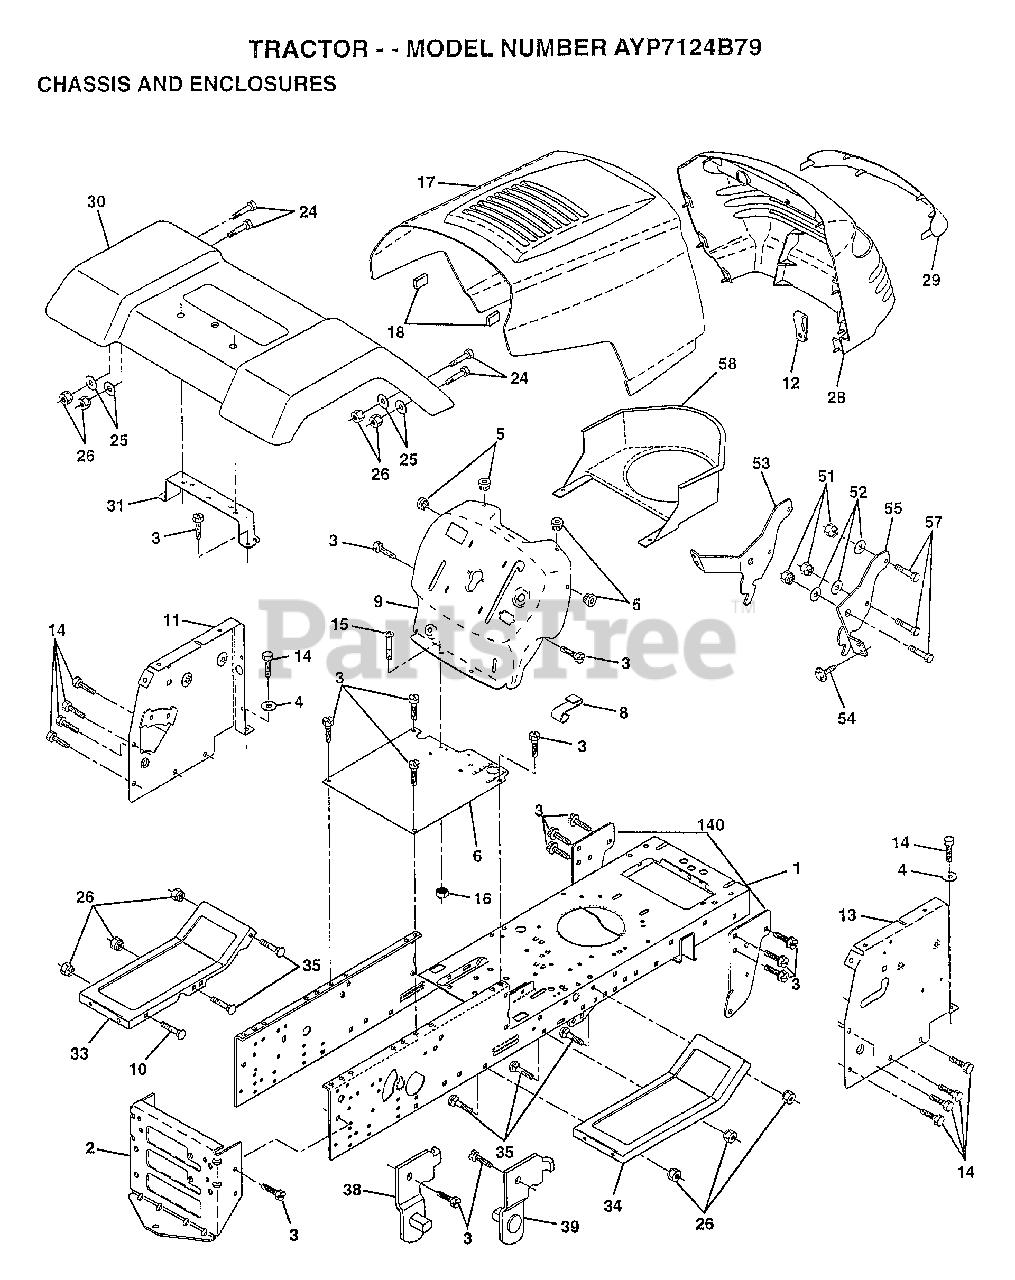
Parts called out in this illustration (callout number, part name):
1	CHASSIS ASM
3	SCREW
4	WASHER
5	BUMPER-HOOD/DASH
6	"SADDLE FLAT,SLKSC"
8	"CLIP,INSULATOR"
9	DASH.SILKSCREENED
11	"PANEL-DASH,LH"
12	CLIP.TINNERMAN
14	SCREW LT
15	BOLT
24	BOLT
25	WASHER
26	NUT
28	GRILLE-MS428
29	LENS GRILLE
30	FENDER
31	BRKT FENDER
33	FOOTREST LH
34	FOOTREST RH
35	BOLT
38	BRACKET ASM LH
39	BRACKET ASM RH
51	NUT
52	WASHER
53	BRACKET.GRILLE.LH
55	BRACKET.GRILLE.RH
58	AIR DUCT
140	BRKT SUSPENSION
145	"ROD POVOT,CHASSIS"
147	BOLT LT
